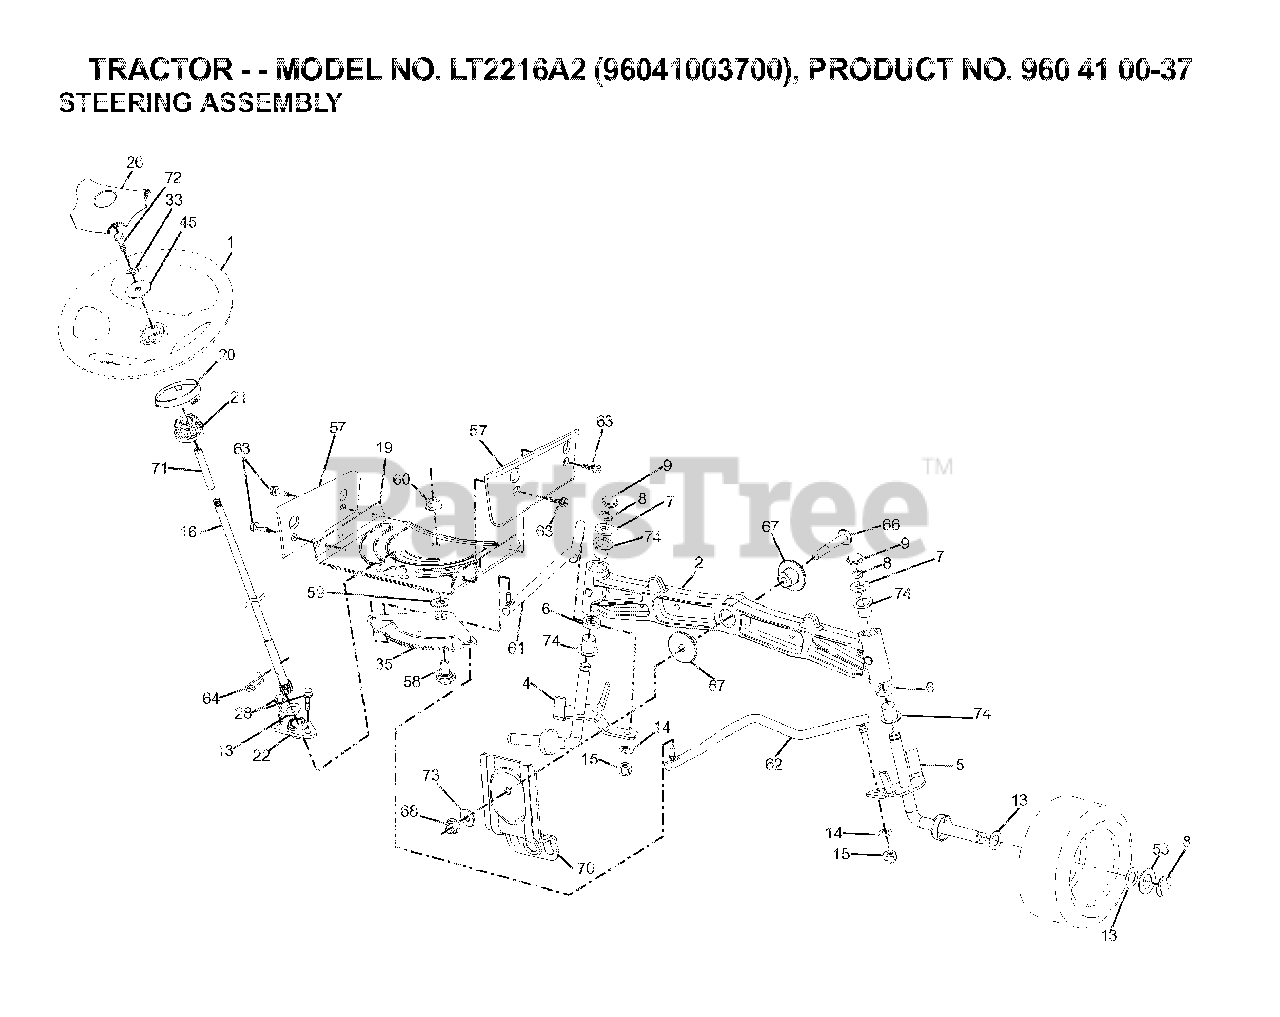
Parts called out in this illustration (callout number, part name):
1	WHEEL.STEERING.PREM.2.BLK
2	AXLE.HALF.ASM.WELDED
4	SPINDLE.WELDED.LH.15"TEX
5	SPINDLE.WELDED.RH.15"T
8	RING CLIP
9	CAP.SPINDLE
14	WASHER, LOCK 3/8
15	NUT CROWNLOCK 3/8-24
16	SHAFT STEERING
19	PLATE.STEER.DDL.NLT/NG
20	BOOT STEERING BLACK
21	ADAPTER, WHEEL STNG..
22	BUSHING.ASM.STEERING.A
26	INSERT.CAP.STRG.WH.BLACK
28	SCREW
33	LOCKWASHER
35	GEAR.SECTOR.PLATE.DDL.
45	WASHER.11/32
53	WASHER.HARDENED
57	BRACKET.UPSTOP.TEX
58	BOLT.SHOULDER.SECTOR.P
59	WASHER.THURST.SECTOR.S
60	NUT FLANGE LOCK 5/8-11
61	DRAGLINK.LH.BALLSTUD.D
62	DRAGLINK.RH.BALLSTUD.D
63	SCREW
64	RETAINER.CLIP.SPRING.S
66	BOLT HEX FGHD 7/16-14 X 3 SERR
67	BUSHING.PM.FRONT AXLE
68	NUT.LOCK.FLANGE.7/16
70	BRKT.DECK.SUSPENSION.F
71	SHAFT EXTENSION STEERING
72	BOLT YT
73	WASHER.1.5X.505X.118
74	BRNG T
